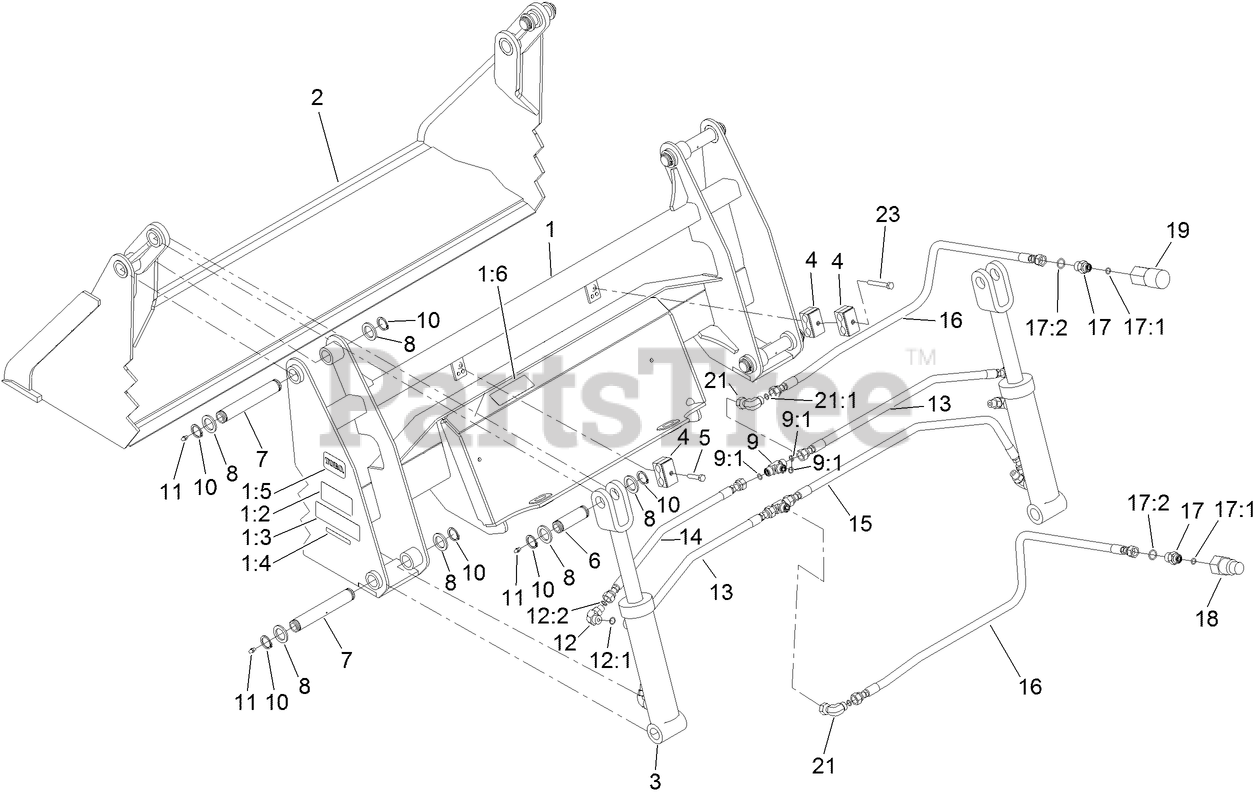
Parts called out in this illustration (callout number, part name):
1	FRAME- 4-IN-1
1:2	DECAL-DANGER
1:3	DECAL- WARNING, CRUSHING
1:4	DECAL-WARNING
1:5	DECAL
1:6	DECAL-CAPACITY
3	CYLINDER-HYD
4	CLAMP-HOSE
5	SCREW-HH
6	PIN-PIVOT
7	PIN-HINGE
8	SPACER-HARDENED
9:1	O-RING
10	RING-RETAINING
11	FITTING-ZERK
12	FITTING-ELBOW, 90 DEG
12:1	O-RING
12:2	O-RING
13	HOSE-HYD
14	HOSE ASM- HYD
15	HOSE ASM- HYD
16	Hose-HYD
17	FITTING-STRAIGHT
17:1	O-RING
17:2	O-RING
18	COUPLER-MALE
19	COUPLER-FEMALE
21	FITTING-HYD, 90 DEG
21:1	O-RING
23	SCREW-HH
